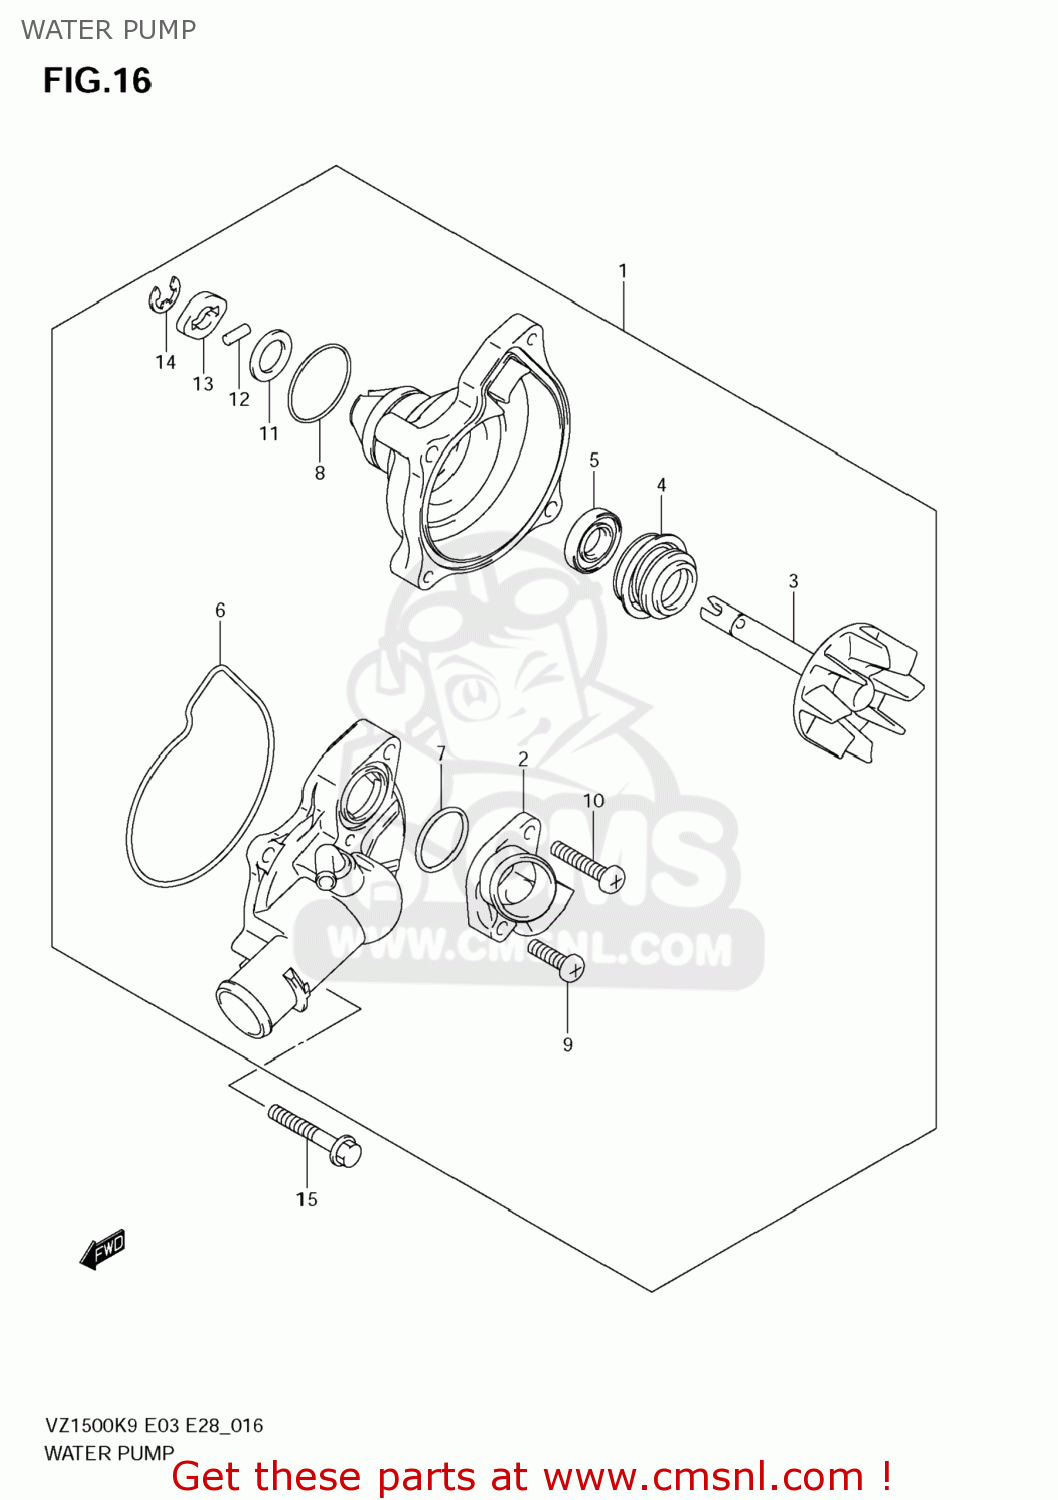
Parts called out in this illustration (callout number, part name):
1	PUMP ASSY,WATER
2	CONNECTOR
3	IMPELLER
4	SEAL,MECHANICAL
5	SEAL,OIL
6	O RING
7	O RING
8	O RING,WATER PUMP HOLDER
9	SCREW
10	SCREW
11	WASHER
12	PIN
13	CAP
14	E RING
15	BOLT
